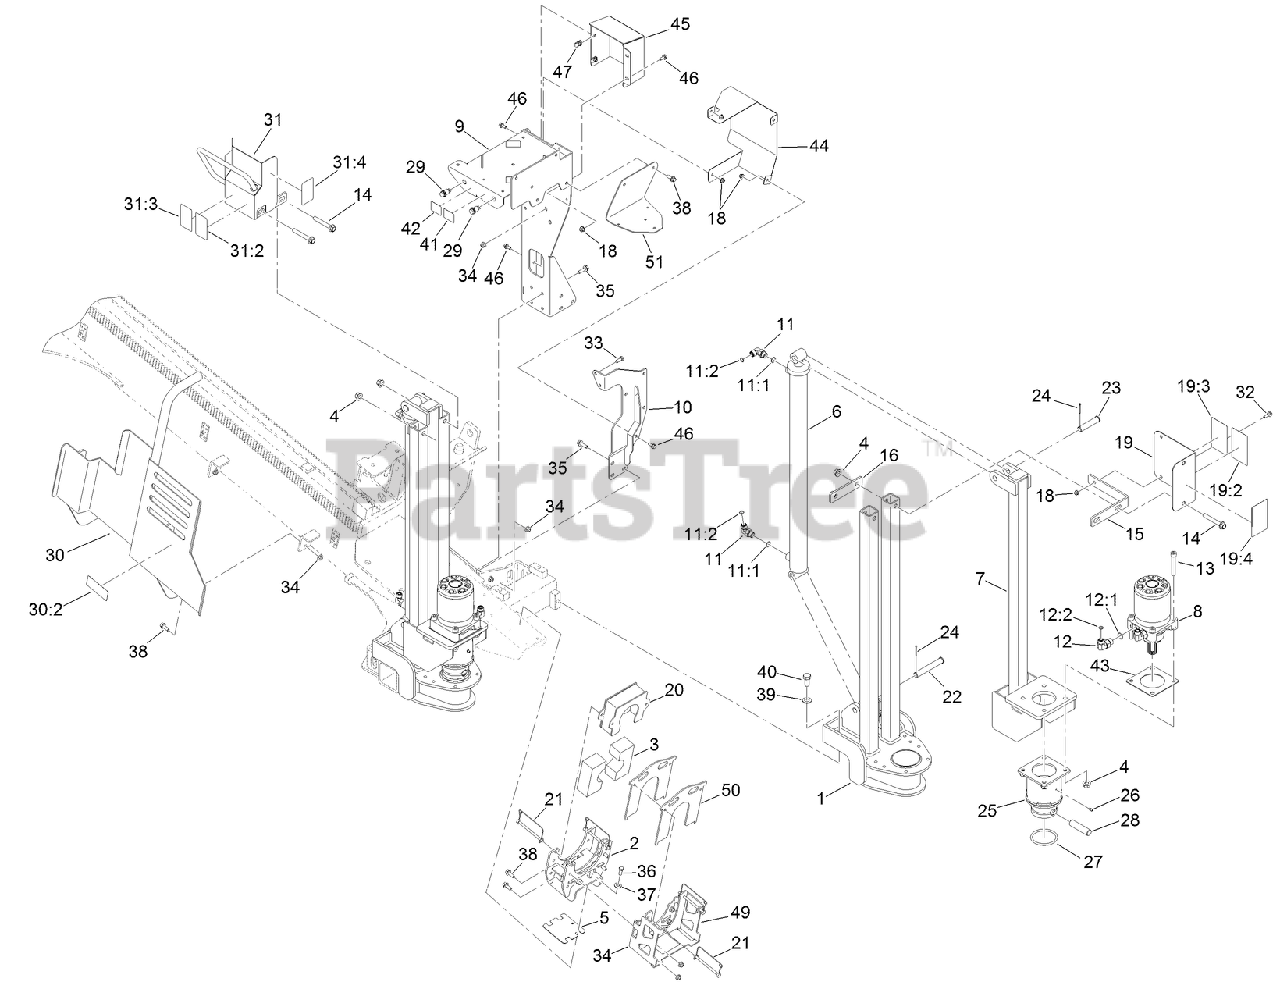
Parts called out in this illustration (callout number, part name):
1	SUPPORT-DOWN, STAKE
2	SUPPORT-GUIDE BLOCK/WIPER
3	GUIDE-ROD, BUSHING
4	NUT-LOCK
5	SHIM-ROD GUIDE, BOTTOM
6	HYD CYLINDER ASM
7	STAKEDOWN
8	MOTOR-HYDRAULIC
9	MOUNT-BUCKET, GREASE
10	BRACKET-MANIFOLD
11	FITTING-ELBOW, 90 DEG
11:1	O-RING
11:2	O-RING
12	FITTING-ELBOW, 90 DEG
12:1	O-RING
12:2	O-RING
13	SCREW-HSH
14	SCREW-HHF
15	TIE-POST, STAKEDOWN
16	BRACKET-GUARD
18	NUT-HF, NI
19	CYLINDER GUARD ASM
19:2	DECAL-WARNING, ENTANGLEMENT
19:3	DECAL-DANGER, HAZARDOUS AREA
19:4	DECAL-WARNING, IMPACT HAZARD
20	COVER-GUIDE, ROD
21	PIN-LOCKING
22	PIN-CLEVIS
23	PIN-CLEVIS
24	PIN-COTTER
25	COUPLER-STAKE DOWN
26	FITTING-GREASE
27	O-RING
28	PIN-STAKE
29	LAMP-INDICATOR, LED
30	FOOT GUARD ASM
30:2	DECAL-DANGER
31	STAKEDOWN HANDLE ASM
31:2	DECAL-WARNING, ENTANGLEMENT
31:3	DECAL-DANGER, HAZARDOUS AREA
31:4	DECAL-WARNING, IMPACT HAZARD
32	SCREW-HHF
33	SCREW-HH
34	NUT-HF, NI
35	SCREW-HHF
36	SCREW-HH
37	WASHER-FLAT
38	SCREW-HHF
39	WASHER
40	SCREW-HH
41	DECAL-PIPE BREAKOUT, CLEAR
42	DECAL-PIPE RETURN CLEAR
43	PLATE-SPACER, MOTOR
44	COVER-MANIFOLD
45	COVER-CONTROLLERS
46	SCREW-HHF
47	NUT-U
49	SUPPORT-WIPER, ROD
50	PLATE-HOLDER, BAR
51	BRACKET-TRAM LIGHT, FRONT
